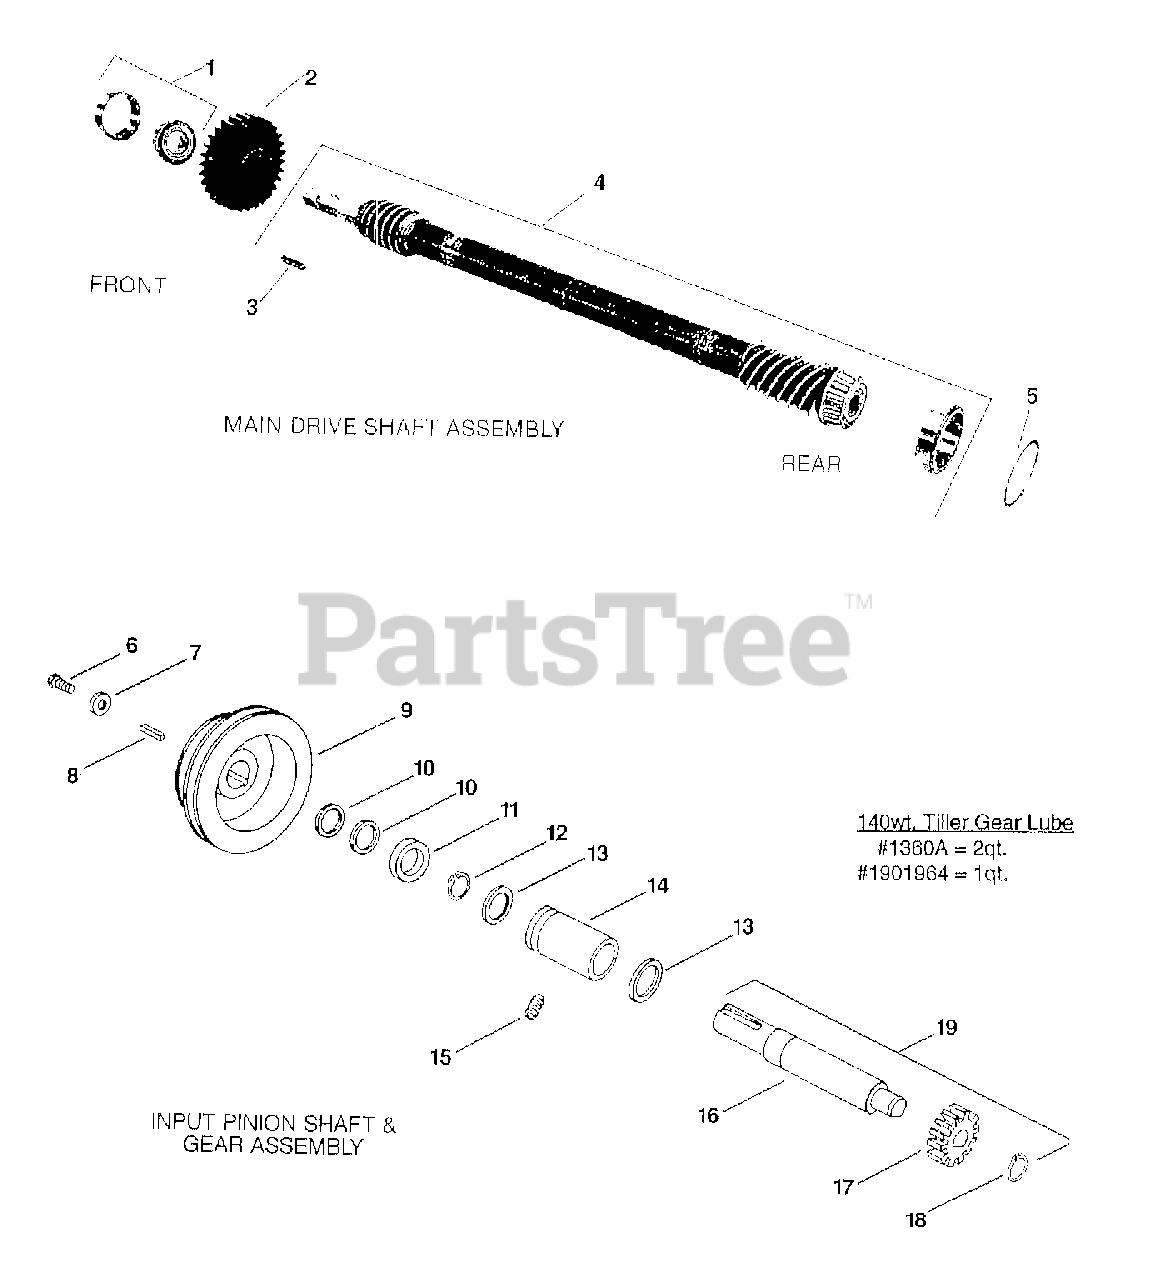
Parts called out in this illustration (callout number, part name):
1	BEARING-tapered roller with race (front of driveshaft)
2	GEAR-spur, main drive shaft
3	KEY-3/16" sq. x 1"
4	DRIVE SHAFT-inertia welded shaft with welded, single-lead hardened steel worm at front to drive the wheel worm gear, and welded six-lead hardened steel worm at rear to drive the tiller gear
5	SHIM- rear bearing cap, .010" thick
5	SHIM-same as above, but .030" thick
5	SHIM- same as above, but .005" thick
6	BOLT-hex head, 5/16"-24 x 3/4" (Grade 5)
7	WASHER-disc spring (concave surface faces pulley)
8	KEY-3/16" sq. x 1"
9	PULLEY-transmission drive pulley, 2 grooves
10	WASHER-support
11	OIL SEAL-input pinion shaft, front
12	RING -retaining (snap ring), external
13	WASHER-thrust
14	BUSHING-
15	SET SCREW-5/16"-18 x 3/8"
16	INPUT PINION-steel shaft
17	GEAR-input pinion
18	RING-retaining (snap ring), external
19	PINION ASSEMBLY-
